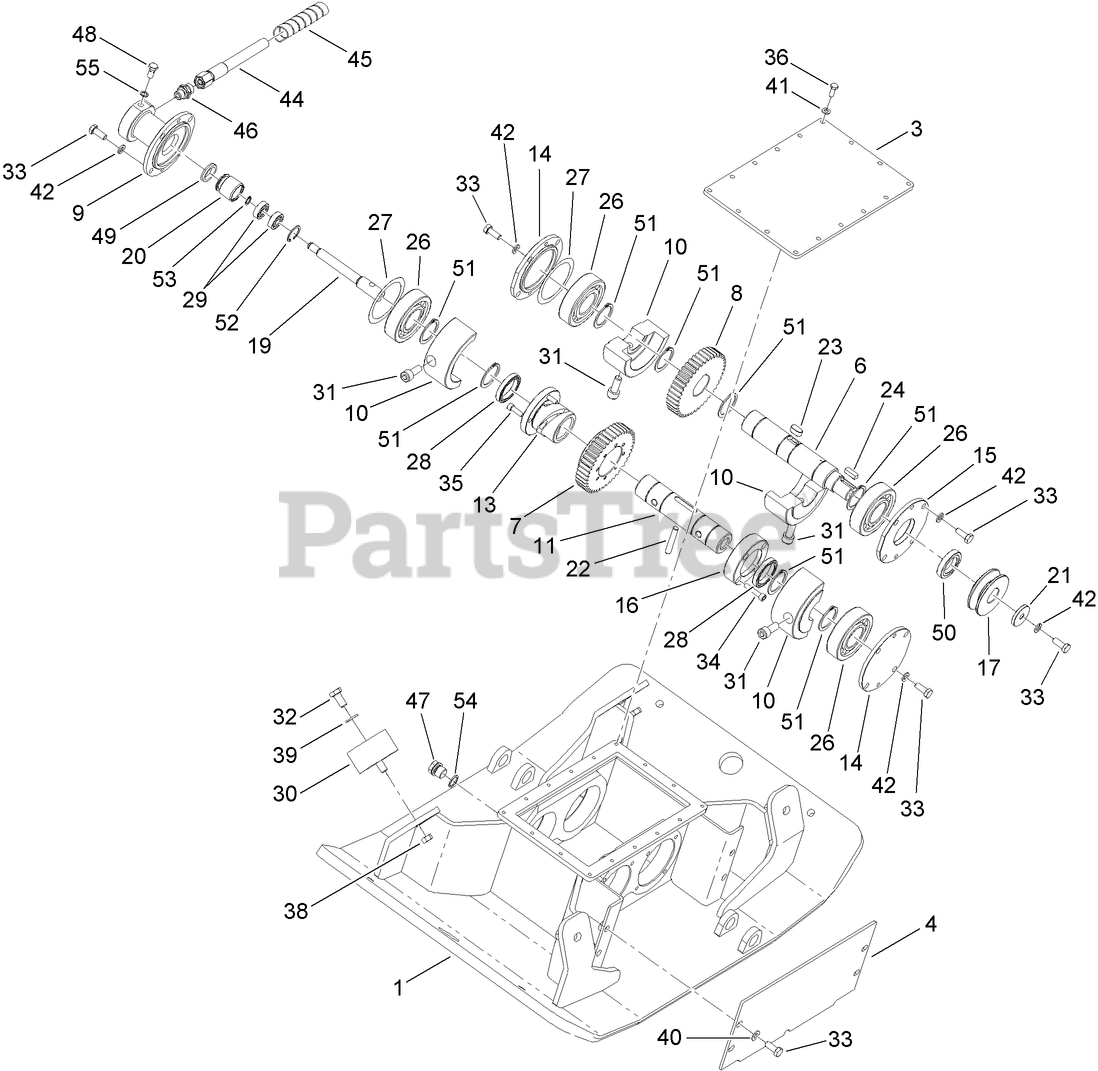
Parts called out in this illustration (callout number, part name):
1	PLATE-BASE
3	COVER-TOP
4	COVER-SIDE
6	SHAFT-INPUT
7	WHEEL-TOOTH II
8	WHEEL-TOOTH I
9	FLANGE-MOUNTING
10	WEIGHT-ECCENTRIC
11	SHAFT-ECCENTRIC, DRIVEN
13	BUSHING
14	COVER-BEARING
15	COVER-BEARING
16	RING-CLAMP
17	PULLEY
19	ROD-SHIFT
20	PISTON-SHIFT
21	WASHER
22	PIN-SHIFTING
26	BEARING-BALL
27	WASHER-DISTANCE
28	BEARING
29	BEARING
30	MOUNT-RUBBER
32	SCREW-HH
38	NUT-LOCK, NI
39	WASHER
40	WASHER
41	WASHER
42	WASHER-LOCK
44	HOSE-HYD
45	COVER-HOSE
46	SOCKET
48	BOLT-FLOW
49	PACKING
50	RING-PACKING
51	RING-LOCKING
52	RING-LOCKING
53	RING-PACKING
55	RING-COPPER
